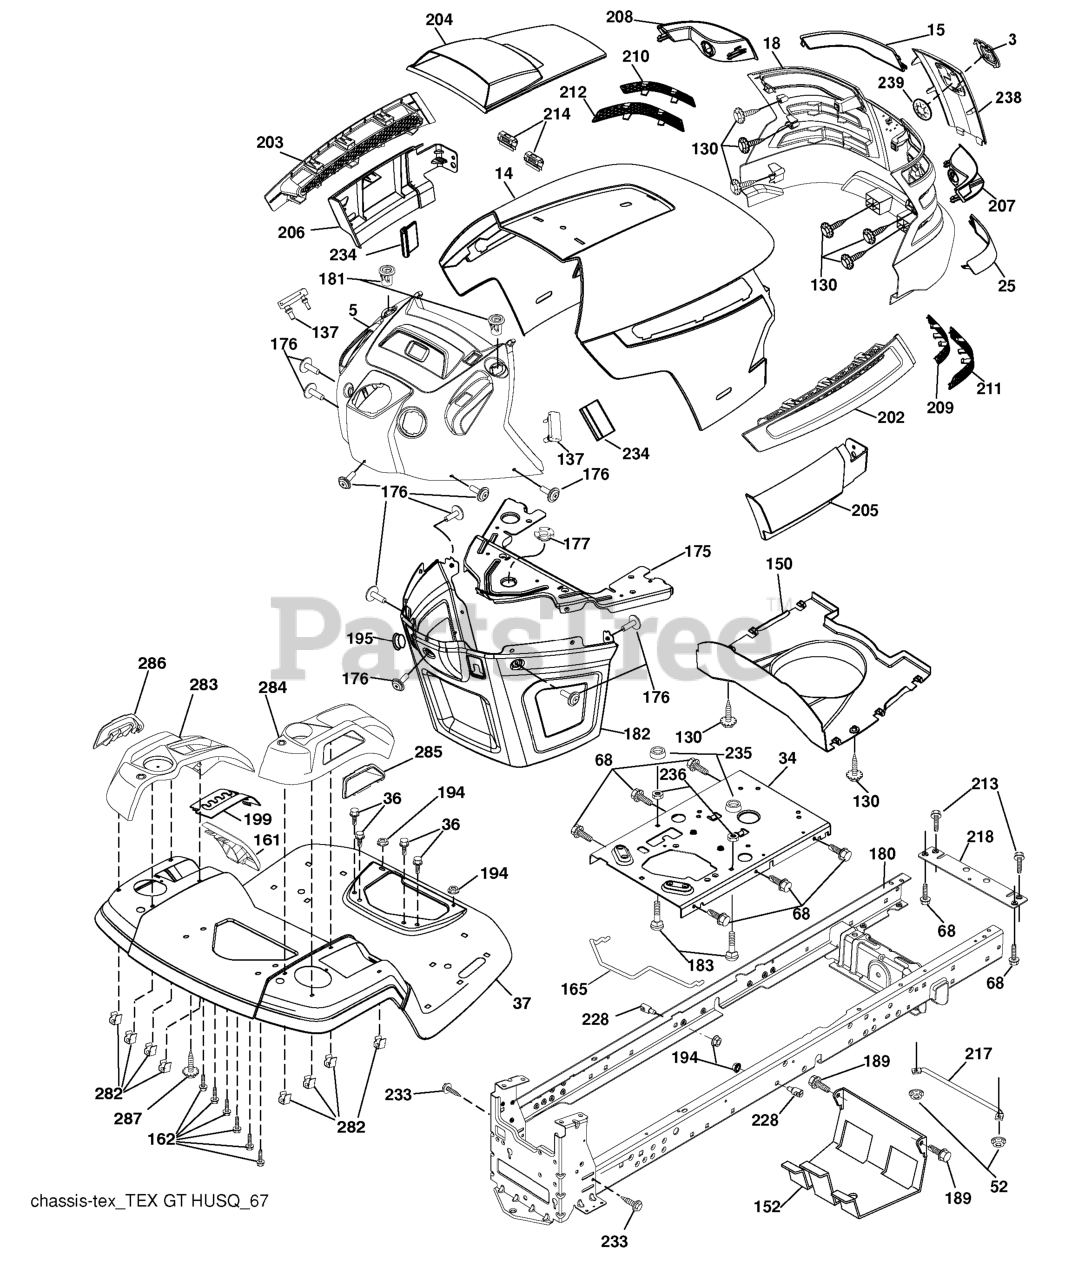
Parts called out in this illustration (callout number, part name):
3	RP LOGO
5	DASH.ASM.HUSQ.GT
14	HOOD
15	LENS.LH.TEX.GT.HUSQ.CL
18	GRILL.ASM.HUSQ.TG/CRD.W/TRIM
25	LENS.RH.TEX.GT.HUSQ.CL
34	PLATE.ENGINE.WELDED.CHASSIS
36	SCREW 5/16"
37	FENDER.TLT.FS.W/CPH/FW/RSF.ORN
52	LOCKNUT
68	Screw 5/16-18 x 1/2
130	SCREW.#10 X 0.750.BOS
137	BUMPER DASH
150	AIR.DUCT.HOOD.TEX.GT.HUSQ
152	SHIELD.BROWNING.W/TEX
161	WINDOW FUEL
162	SCREW.HI-LO.CONSOLE
165	SUPPORT.TANK.REAR.W/TEX
175	PLATE.CROSSMEMBER.HUSQ
176	SCREW.#10-24X5/8.RN.QU
177	BUSHING, STEERING
180	CHASSIS
181	BUSHING.MNT.FEND.CRGO.
182	DASH.LOWER.COMMON.12V.ADAPTOR
183	BOLT.5/16-18X1-1/4 FULL.THREAD
189	SCREW
194	NUT LOCK HEX FLANGE 5/16-18
195	PLUG.HOLE.DASH.LOWER.12V.BLK
199	PLATE.DECK.LIFT.HUSQ.LT
202	VENT.SIDE.HOOD.HUSQ.RH.GREY
203	VENT.SIDE.HOOD.HUSQ.LH.GRAY
204	HOOD VENT
205	SKIRT.HOOD.SIDE.HUSQ.RH.GREY
206	SKIRT.HOOD.SIDE.HUSQ.LH.GREY
207	BEZEL.RH.TEX.GT.HUSQ
208	BEZEL.LH.TEX.GT.HUSQ
209	INSERT.HEX.GRILL.HUSQ.GREY
210	INSERT.HEX.GRILL.HUSQ.
211	INSERT.HEX.GRILL.HUSQ.
212	INSERT.HEX.GRILL.HUSQ.
213	BOLT
214	CLIP.RETAINER.TINNER.
217	ROD.PIVOT.HOOD
218	X-PIECE.HOOD.STOP.NON/
228	STUD.FASTNER.W/ANTI-ROTATE
233	BOLT.SHOULDER
234	BUMPER.HOOD.TEX.HUSQVARNA
235	SPACER FENDER
236	NUT.CENTERLOCK.5/16-
238	TRIM.HUSQ.TG/CRD.SERVICE
239	NUT PUSH M
282	CLIP.RETAINER.CONSOLE.LT.HUSQ
283	RP CONSOLE ASM.DECKLFT.RSF.
284	RP CONSOLE ASM.PDL CNTRL.HUSQ
285	CONSOLE INSERT RH
286	CONSOLE.INSRT.LH.HUSQ.LT.BLACK
287	SCREW 1/4X20
